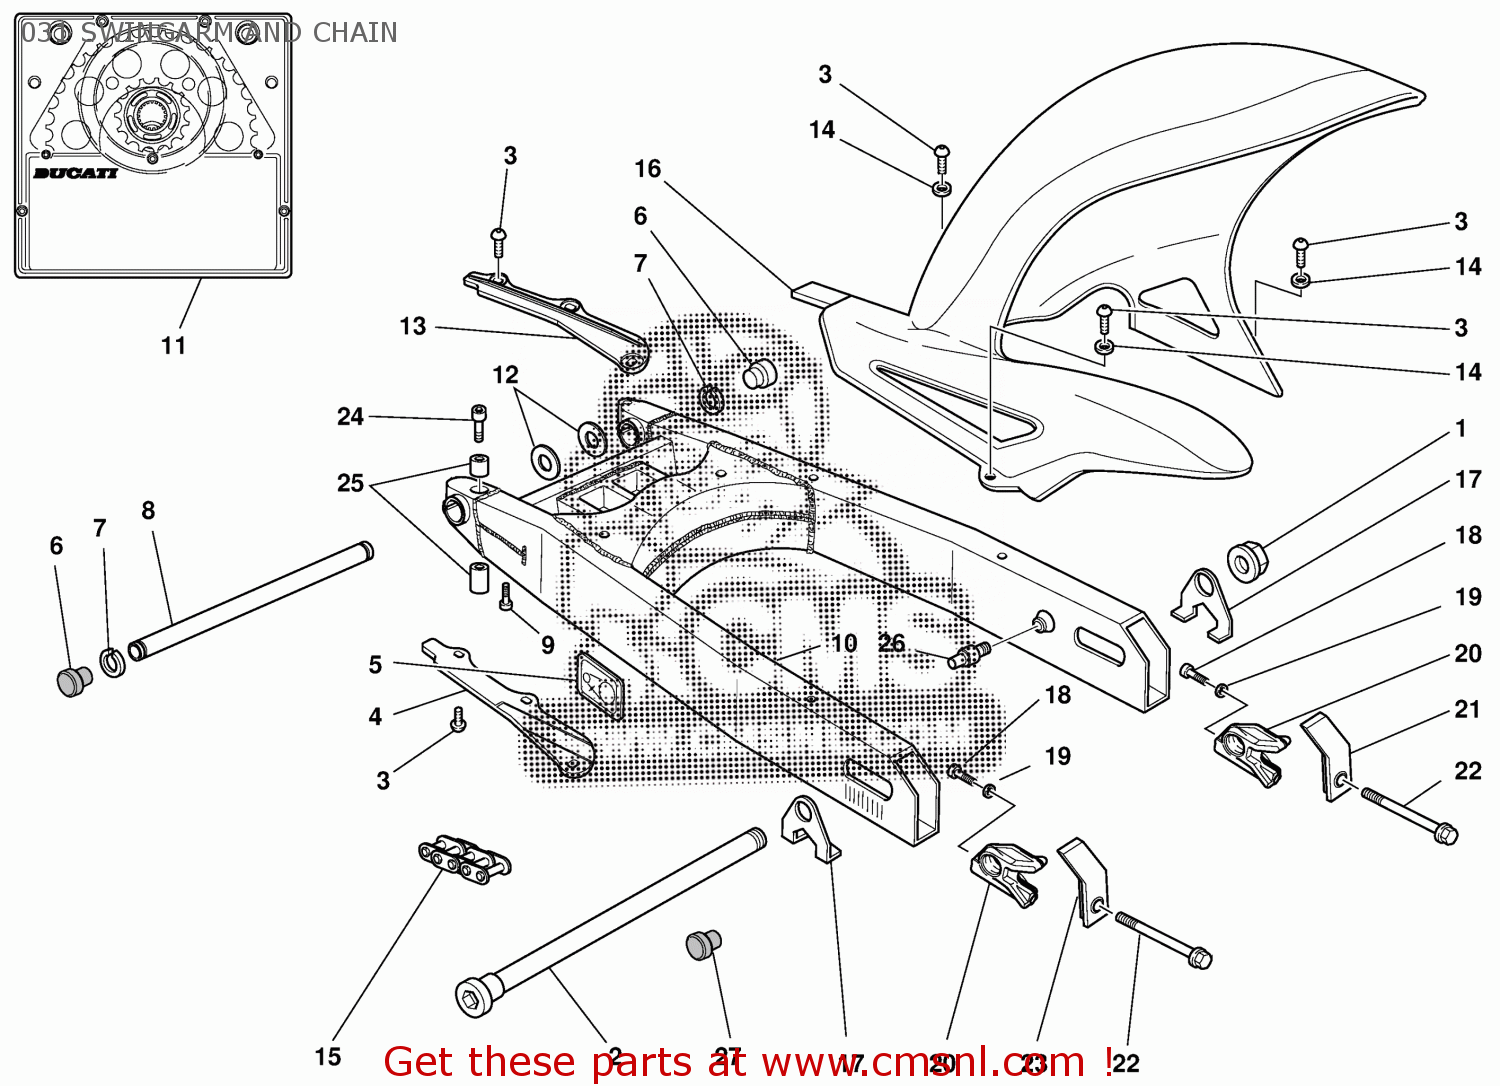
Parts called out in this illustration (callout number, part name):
1	NUT
2	REAR WHEEL SPINDLE
3	SCREW M6X20
4	LOWER CHAIN SLIDING SHOE
5	STICKER, ADJUSTING CHAIN
6	PLUG
7	SPRING RING
8	AXLE, REAR SWING ARM
9	SCREW M8X25
10	SWING ARM
11	FINAL DRIVE KIT
12	THRUST WASHER 1.8 MM
13	UPPER CHAIN SLIDING SHOE
14	GASKET NYLON
15	CHAIN
16	REAR MUDGUARD
17	PLATE CHAIN TIGHTENER
18	SCREW M3X8
19	WASHER 3.2X8X1.5
20	SLIDING SHOE
21	RIGHT COVER
22	SCREW
23	LEFT COVER
24	SCREW TCEI M8X1.25X30
25	PIN
26	LOCATING PIN
27	PLUG
